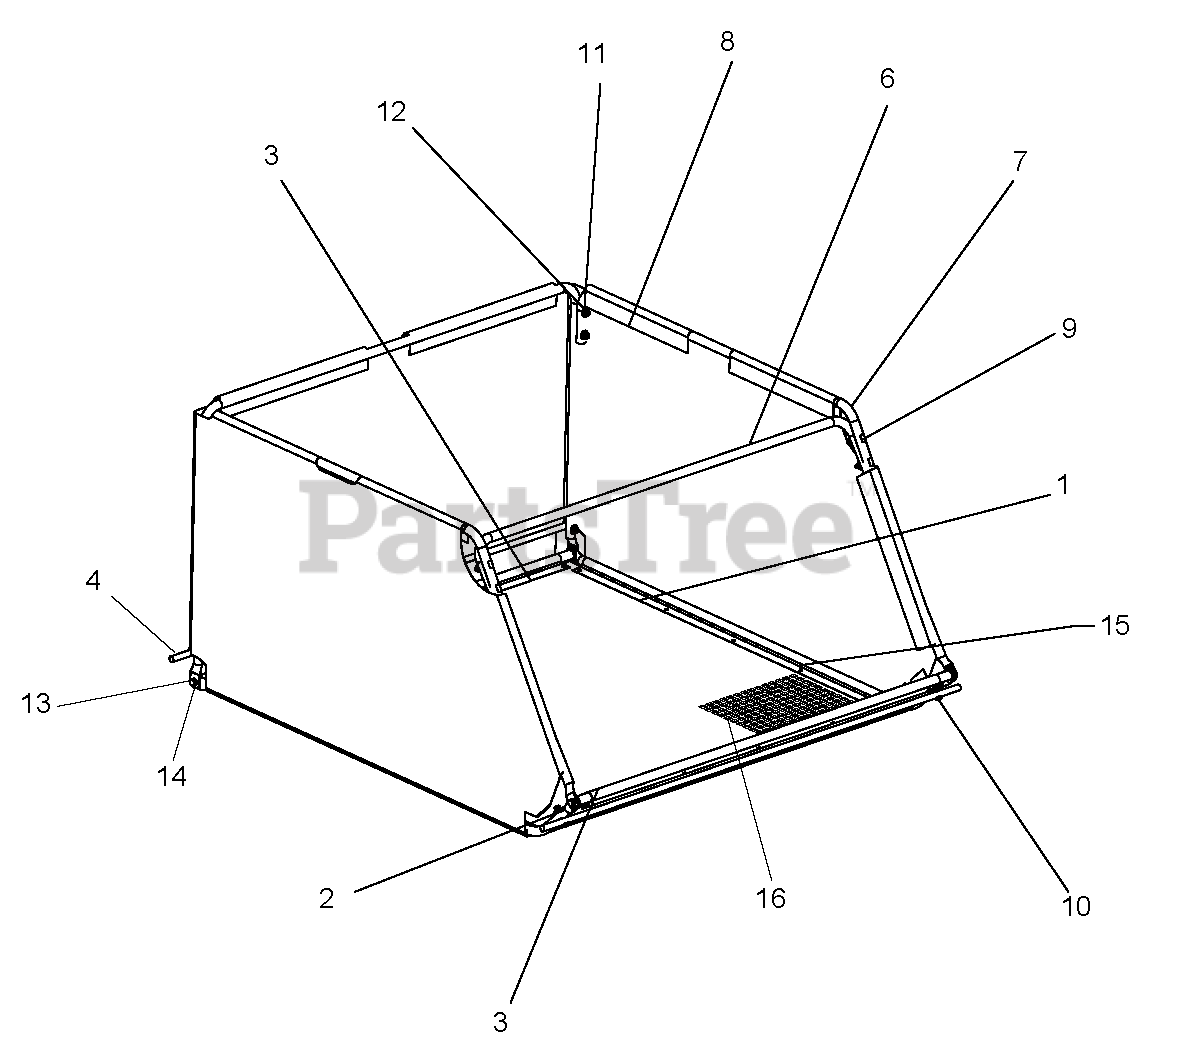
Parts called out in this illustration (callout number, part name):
1	Basket Clamp Assembly
2	Basket Clamp Assembly
3	Basket Clamp Assembly
4	Support Rod
5	Rear Upright
6	Front Upright
7	Frame Basket Side Top
8	Basket Assembly
9	Bolt, 1/4-20 x 2.0 Contour Hd.
10	Bolt, 1/4-20 x 1.5 Hex 5
11	Washer, 1/4 Flat
12	Nut, 1/4-20 Nyloc
13	Washer, 5/16 Spring Lock
14	Bolt, 5/16-18 x 1.00 Hex 5
15	Rivet, Bulb Tite
16	Basket Bottom, Mesh
